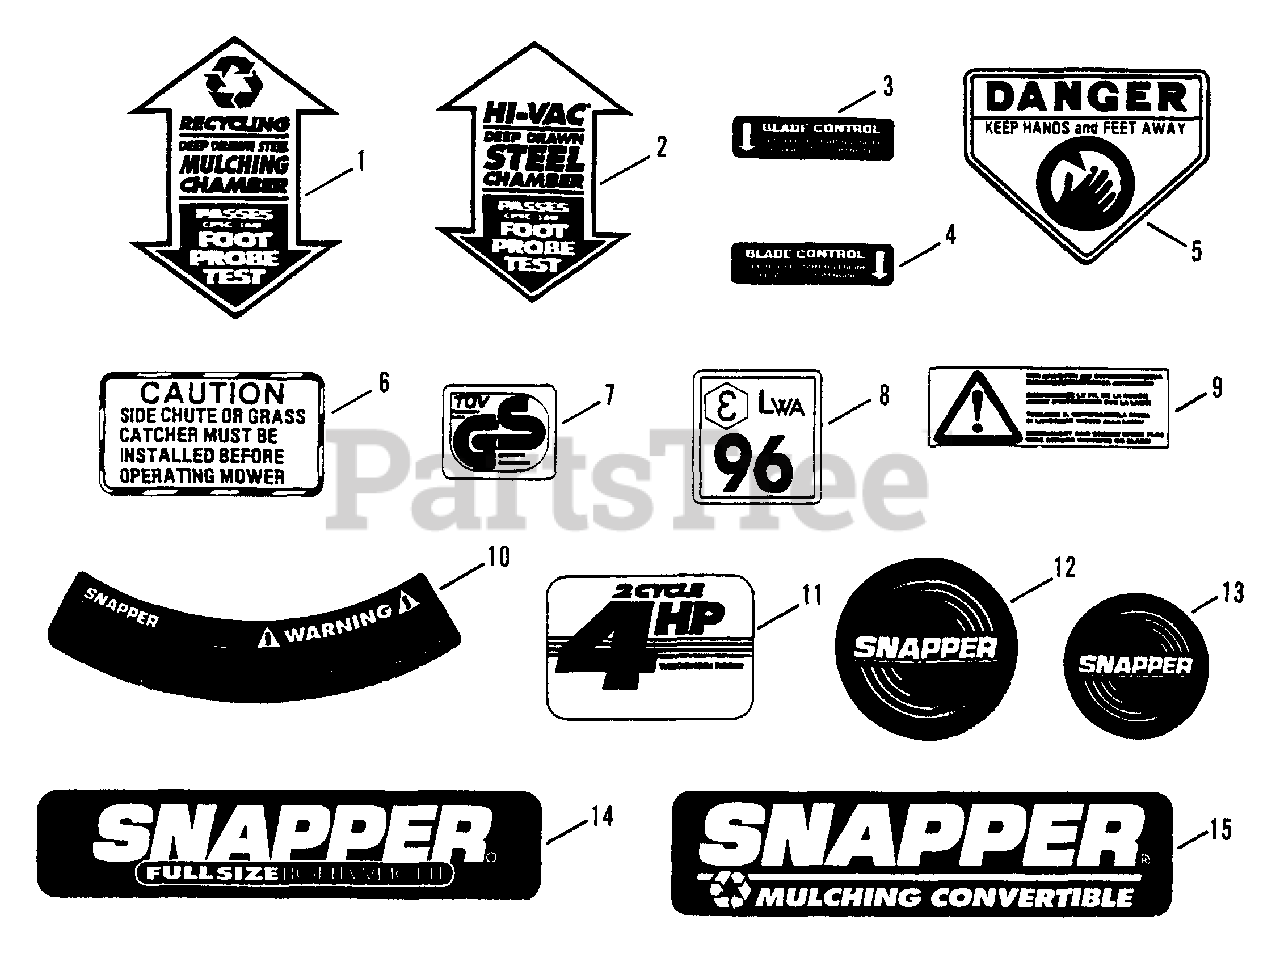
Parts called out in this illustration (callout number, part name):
1	DECAL, Recycling / Foot Probe
2	DECAL, Hi-Vac / Foot Probe
3	DECAL, Blade Control
4	DECAL, Blade Control
5	DECAL, Warning
6	DECAL, Caution
7	DECAL, G.S.
8	DECAL, Noise Control
9	DECAL, Spark Plug
10	DECAL, Blank (Small)
11	DECAL, 4 HP Robin
12	DECAL, Snapper (3.38 Dia.)
13	DECAL, Snapper (2.50 Dia.)
14	DECAL, Light Weight
15	DECAL, Mulcher Convertible
